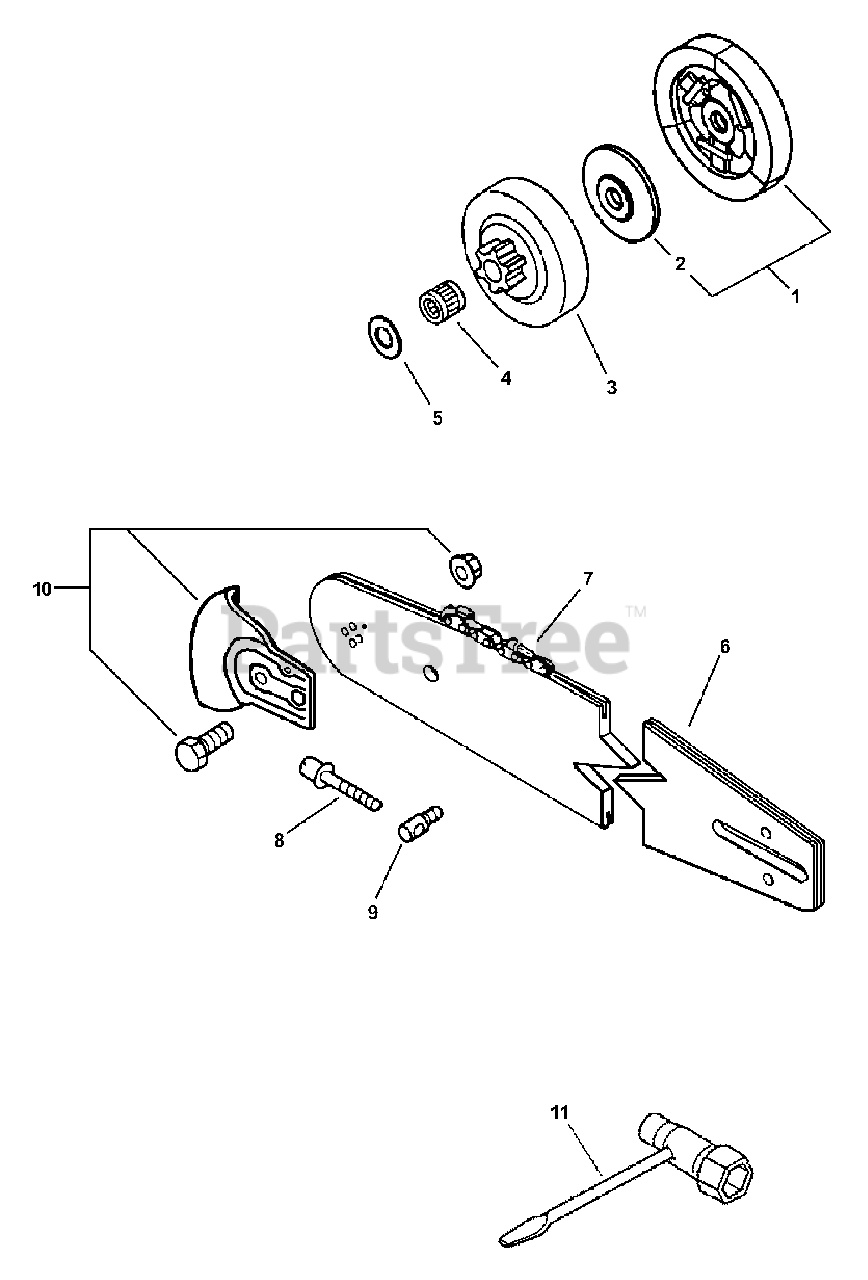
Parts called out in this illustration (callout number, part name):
1	CLUTCH ASSY
2	PLATE, CLUTCH
3	DRUM, CLUTCH
4	BEARING, NEEDLE
6	GUIDE BAR - 12" (30cm)
6	GUIDE BAR - 14" (35cm)
6	GUIDE BAR - 16" (40cm)
7	SAW CHAIN - 12" (30cm)
7	SAW CHAIN - 14" (35cm)
7	SAW CHAIN - 16" (40cm)
8	SCREW, TENSIONER
9	TENSIONER, CHAIN
10	KICK GUARD KIT
11	T-WRENCH - 10X19mm
